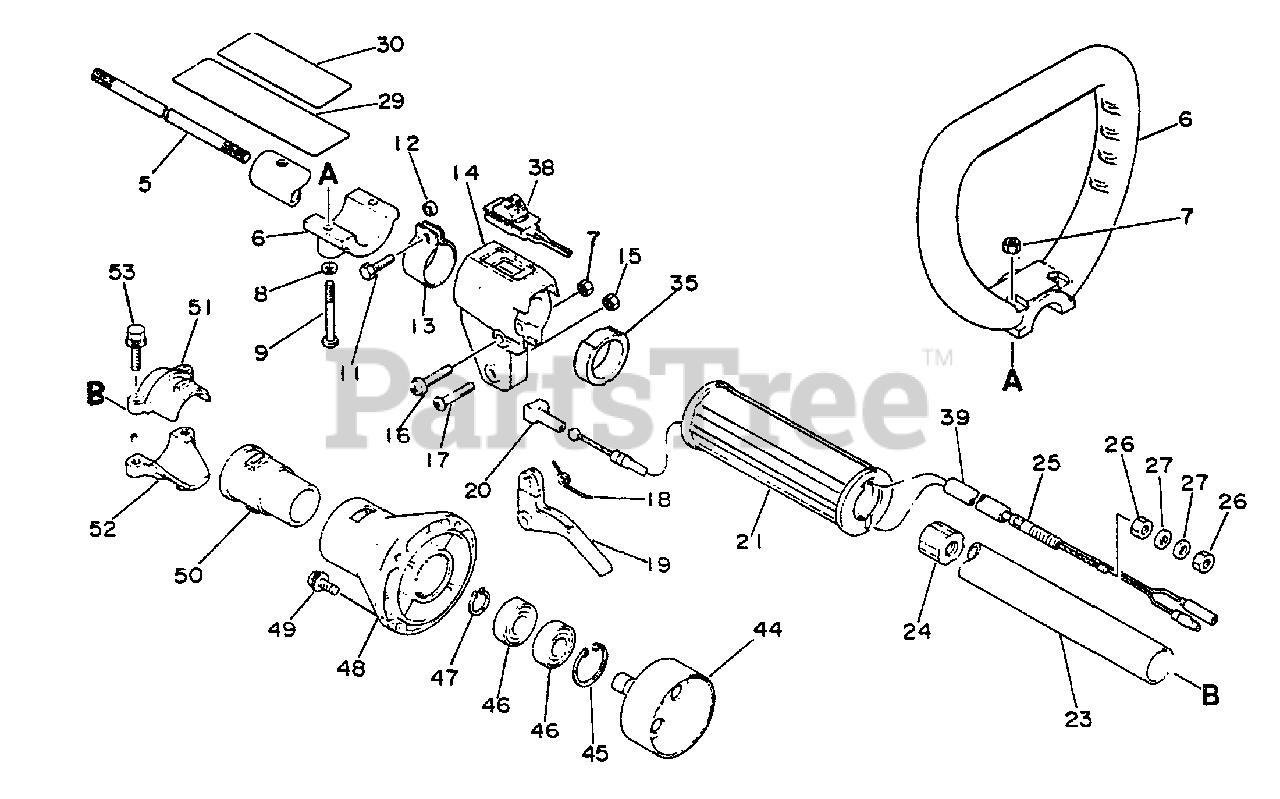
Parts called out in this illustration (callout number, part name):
5	DRIVESHAFT
6	LOOP HANDLE ASSY
8	WASHER - 5
9	SCREW - 5X40
11	BOLT - 5X18
14	BRACKET, THROTTLE CONTROL
15	LOCKNUT - 5
16	SCREW - 5X30
17	SCREW - 5X30
18	SPRING, TRIGGER
19	TRIGGER, THROTTLE
20	GUIDE, CABLE
21	GRIP, HANDLE
23	PIPE, MAIN
24	STOPPER
25	CABLE, THROTTLE
27	WASHER - 6
29	LABEL - CAUTION
30	LABEL - CAUTION
38	IGNITION SWITCH ASSY
39	TUBE - VINYL
44	DRUM, CLUTCH
45	RING, RETAINING - 28
46	BEARING, BALL - 6001
47	RING, RETAINING - 12
48	CASE, CLUTCH - ORANGE
49	SCREW - 5X16
51	CLAMP, MAIN PIPE - UPPER
52	CLAMP, MAIN PIPE
53	BOLT - 5X25
